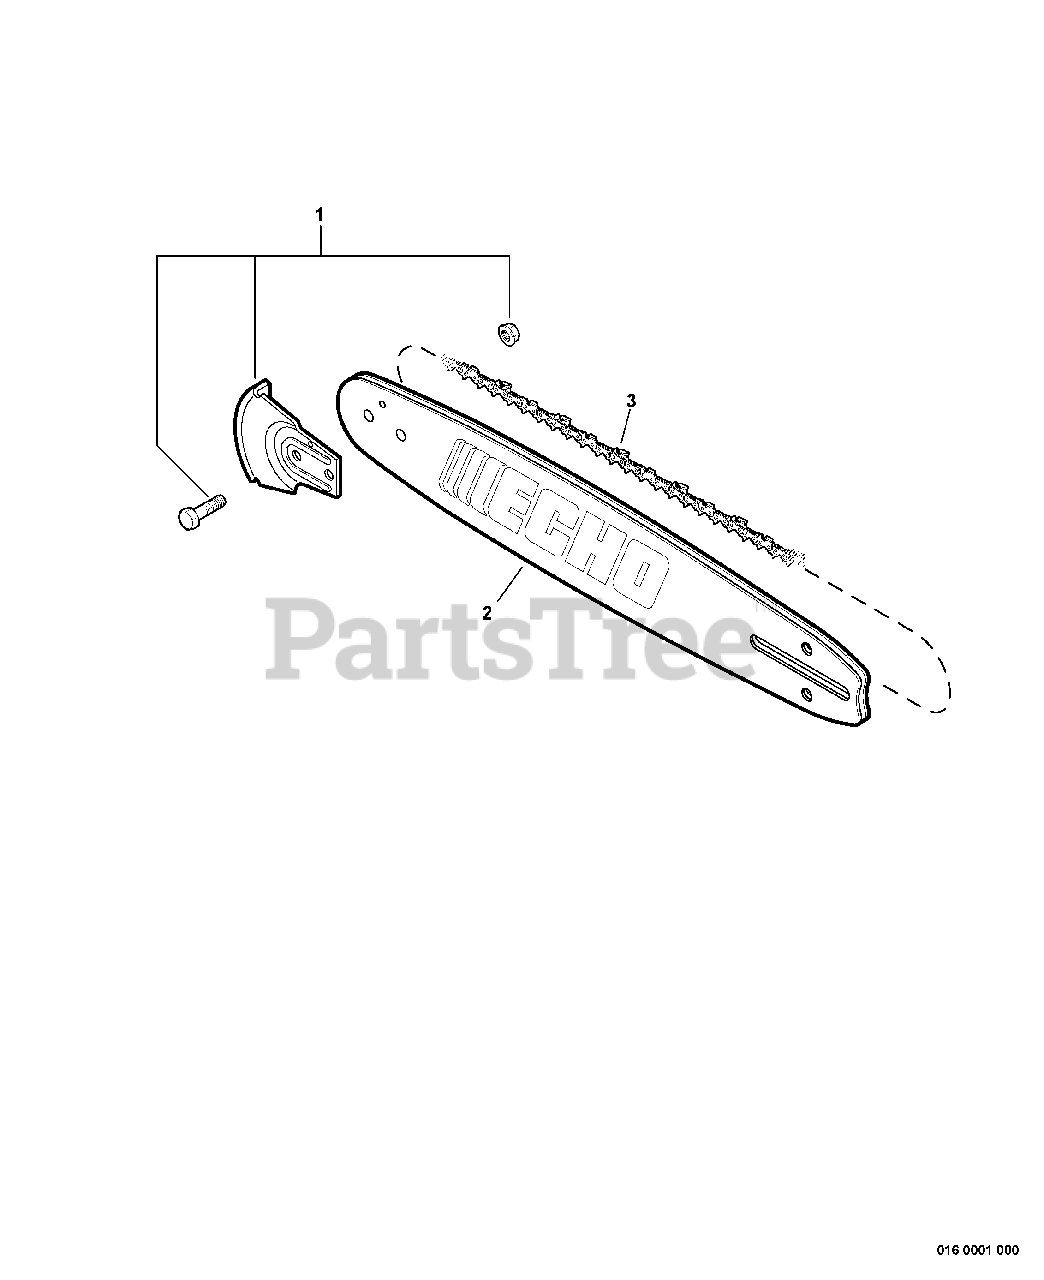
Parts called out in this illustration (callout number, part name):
1	KICK GUARD KIT
2	GUIDE BAR, 14"
3	SAWING CHAIN - 14" -- MICRO-LITE
